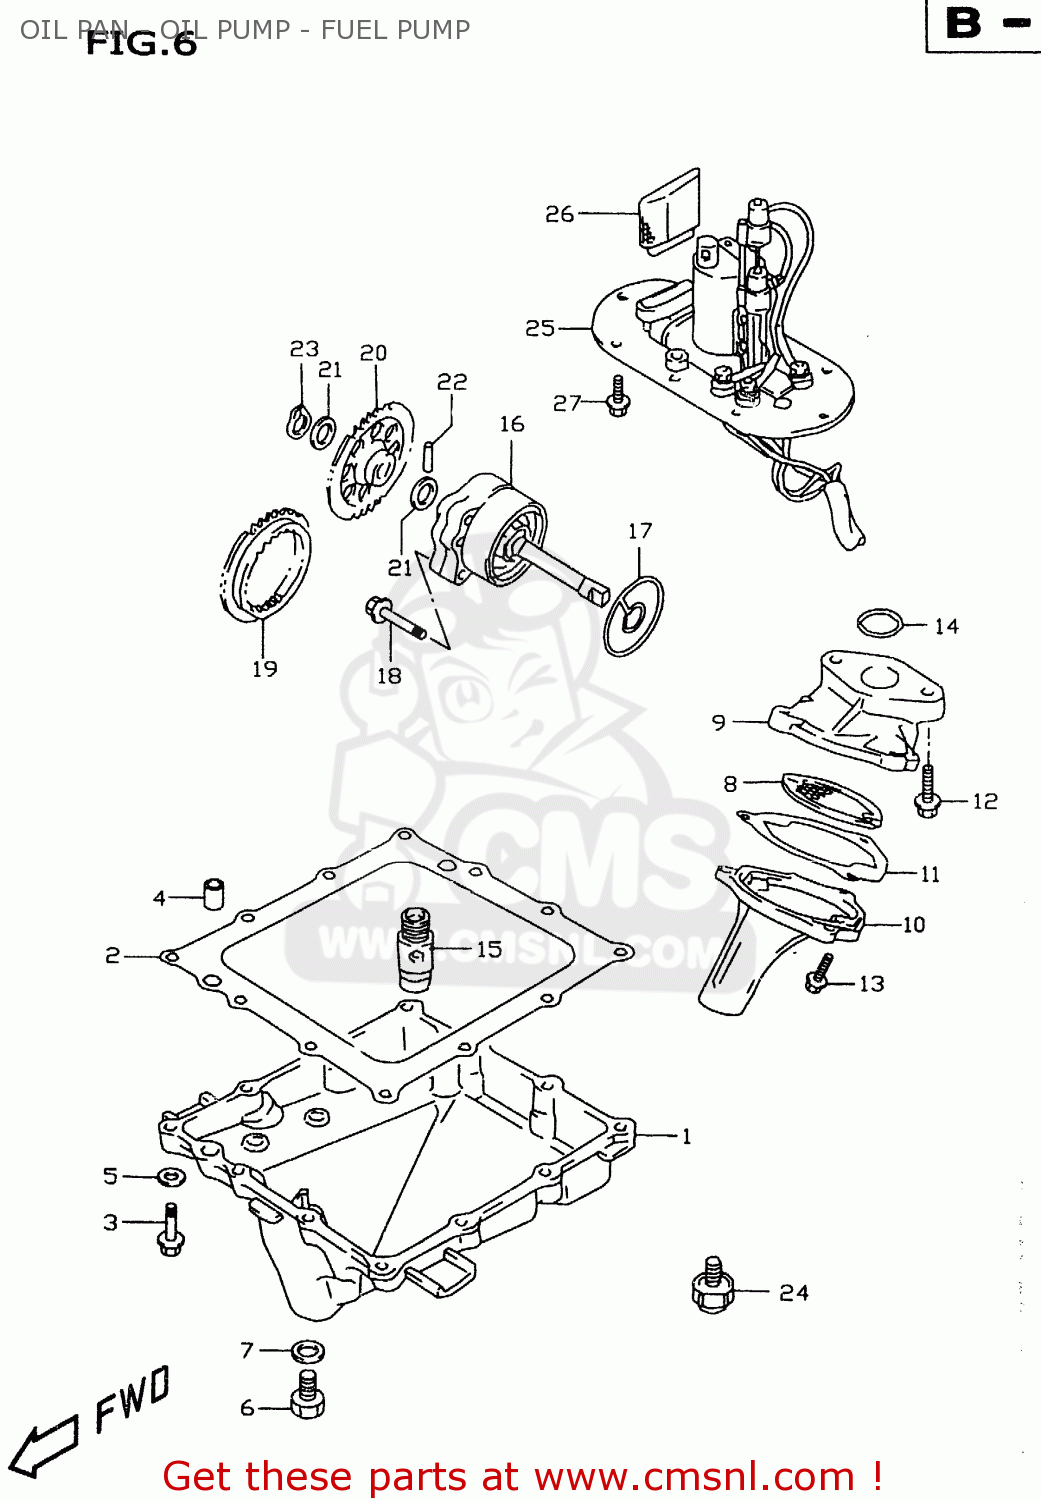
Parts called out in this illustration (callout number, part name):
1	PAN,OIL
2	GASKET,OIL PAN (NAS)
3	BOLT,G/S SWITC
4	PIN
5	GASKET(5.8X11X1.2) (NAS)
6	PLUG
7	GASKET(13.8X18.8X4.8) (NAS)
8	STRAINER,ENGINE OIL
9	PROTECTOR,OIL STRAINER
10	COVER,OIL STRAINER
11	GASKET,OIL STRAINER
12	BOLT
13	BOLT
14	O RING(D:2.62,ID:20.3)
15	VALVE ASSY,OIL RELIEF
16	PUMP ASSY,ENGINE OIL
17	O RING,OIL PUMP
18	BOLT
19	GEAR,OIL PUMP DRIVE
20	GEAR,OIL PUMP DRIVEN
21	SHIM
22	PIN(5X18)
23	CIRCLIP,12 MM
24	SWITCH ASSEMBLY,OIL PRESSURE
25	PUMP ASSY,FUEL
26	STRAINER,FUEL PUMP
27	BOLT
